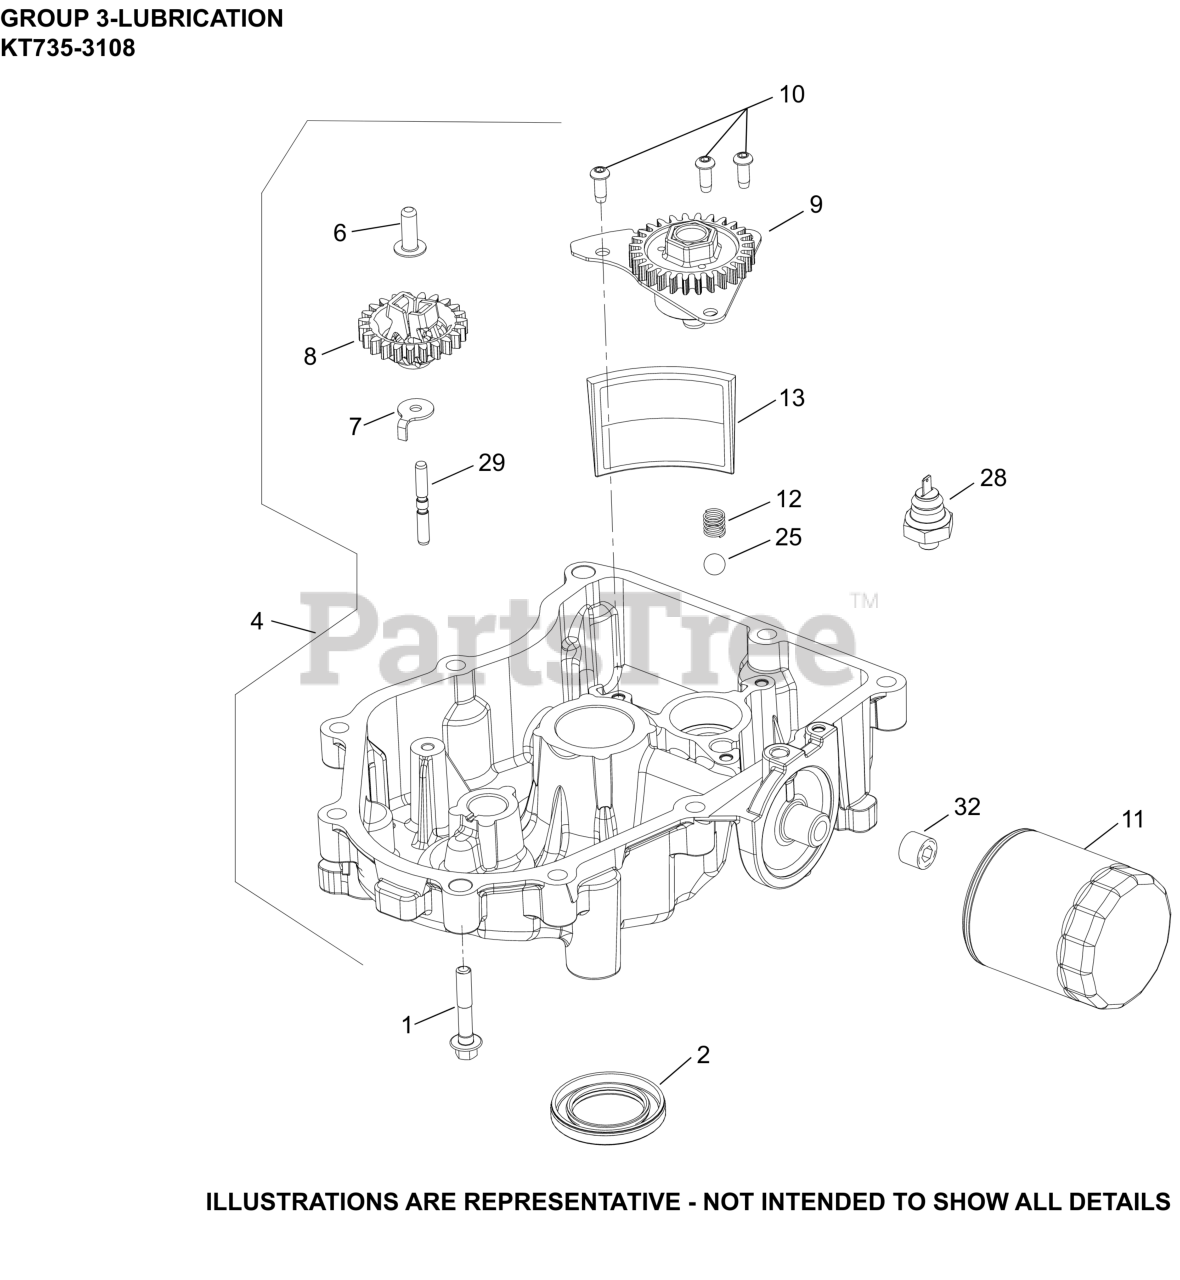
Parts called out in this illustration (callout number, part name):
1	SCREW, FLG M8X1.25X45
4	OIL PAN ASSEMBLY, (ROLLER BURNISHED)
6	PIN, GOVERNOR REGULATING
7	TAB, LOCKING
8	KIT, GOVERNOR GEAR
9	PUMP ASSEMBLY, OIL
10	SCREW, BUTTON HEAD
11	OIL FILTER
12	SPRING, COMPRESSION
13	SCREEN, OIL
25	PRESSURE RELIEF BALL
28	SWITCH, OIL PRESSURE(NC 3-6 PSI TO OPEN)
29	SHAFT, GOVERNOR GEAR
32	PLUG, PIPE CTSK 3/8"
